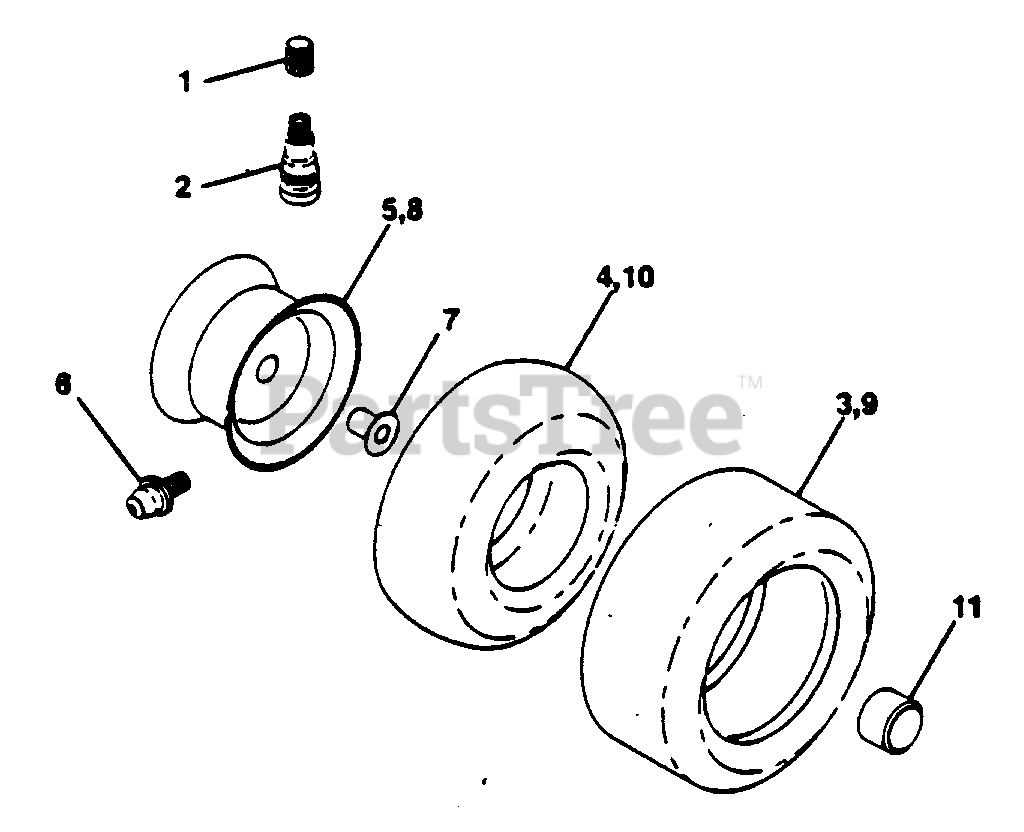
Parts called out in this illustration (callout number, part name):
1	Cap Valve Tire (AYP part number)
2	Stem Valve (AYP part number)
3	Tire F Ts 15 X 6 0 - 6 Service (AYP part number)
4	Tube Front (Service Item Only)
5	Rim Asm 6" front Service (AYP part number)
6	Fitting Grease (Front Wheel Only) (AYP part number)
7	Bearing Flange (Service Item Only) (AYP part number)
8	Rim Asm 8" rear Service (AYP part number)
9	Tire R Ts 18x9 5-8 C Service (AYP part number)
10	Tube Rear (Service Item Only) (AYP part number)
11	Cap Axle Blk 1 50 X 1 00 (AYP part number)
